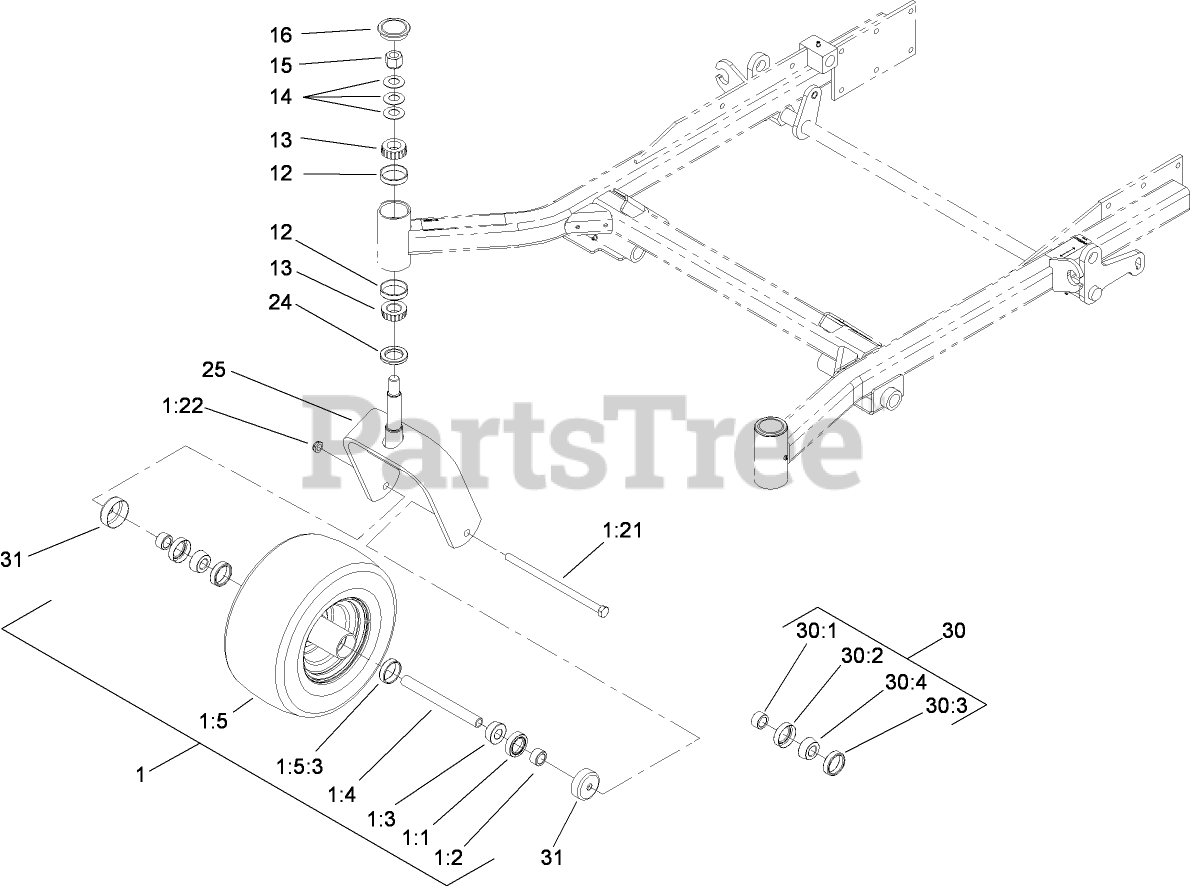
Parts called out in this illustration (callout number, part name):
1	CASTOR WHEEL ASM
1:1	SEAL-BEARING
1:2	SPACER-BEARING
1:3	BEARING-CONE, TAPER
1:4	SPACER-CASTER, FRONT
1:5	WHEEL AND TIRE ASM (SEMI-PNEUMATIC)
1:5:3	BEARING-CUP
1:21	SCREW-HH
1:22	NUT-LOCK, NI
12	BEARING-CUP, TAPERED
13	BEARING-CONE, TAPERED
14	WASHER-BELLVILLE
15	NUT-LOCK, NI
16	CAP-GREASE
24	SEAL-GREASE
25	CASTER
30	CASTER WHEEL BEARING KIT
30:1	SPACER-BEARING
30:2	SEAL-BEARING
30:3	BEARING-CUP
30:4	BEARING-CONE, TAPER
31	GUARD-SEAL
